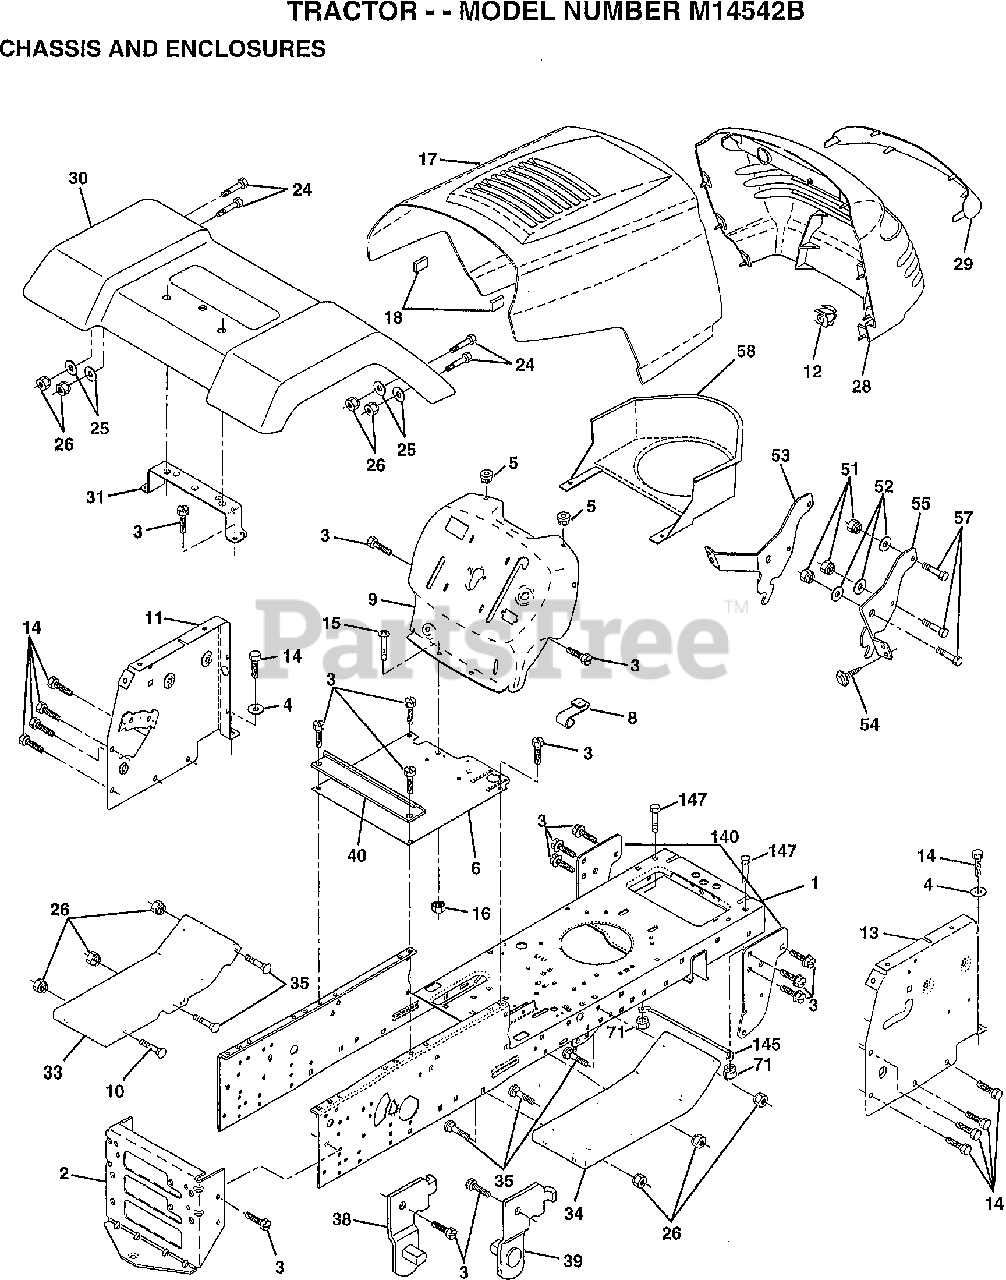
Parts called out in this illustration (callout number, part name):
1	CHASSIS ASM
3	SCREW
4	WASHER
5	BUMPER-HOOD/DASH
6	SADDLE SLKSCR FLAT LT 6SP PEER
8	CLIP.RETAINER
9	DASH.SILKSCREENED
11	"PANEL-DASH,LH"
12	CLIP.TINNERMAN
14	SCREW LT
15	SCREW
24	BOLT
25	WASHER
26	NUT
28	GRILLE-MS428
29	LENS GRILLE
30	FENDER
31	BRACKET SUPT FEND
33	FOOTREST.LH.PERF.
34	FOOTREST.RH.PERF.
35	BOLT
38	BRACKET ASM LH
39	BRACKET ASM RH
40	SPACER FENDER LT
51	NUT
52	WASHER
53	BRACKET.GRILLE.LH
55	BRACKET.GRILLE.RH
58	AIR DUCT
140	BRKT SUSPENSION
145	"ROD POVOT,CHASSIS"
147	BOLT LT
